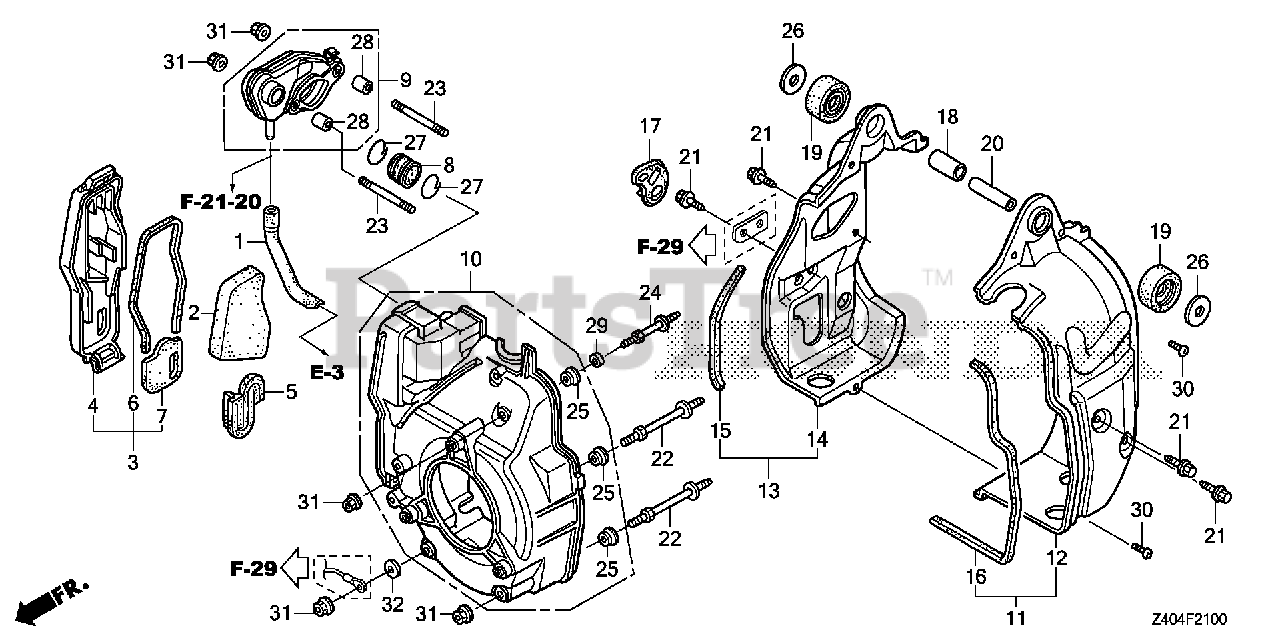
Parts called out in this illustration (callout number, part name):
1	TUBE, BREATHER
2	ELEMENT, AIR CLEANER
3	COVER, AIR CLEANER
4	COVER, AIR CLEANER
5	RUBBER, AIR CLEANER
6	SEAL A, AIR CLEANER COVER
7	SEAL B, AIR CLEANER COVER
8	TUBE, AIR CLEANER CONNECTING
9	JOINT, AIR IN.
10	COVER, FAN
11	SHROUD ASSY., R.
12	SHROUD, R.
13	SHROUD ASSY., L.
14	SHROUD, L.
15	SEAL A, SHROUD
16	SEAL B, SHROUD
17	RUBBER, OIL CHECK
18	COLLAR D, INSULATOR
19	INSULATOR, SHROUD
20	COLLAR B, INSULATOR
21	BOLT, FLANGE (5X10)
22	BOLT A, STUD
23	BOLT, STUD (5X91)
24	BOLT B, STUD
25	COLLAR, REFLECTOR SETTING
26	WASHER, SPROCKET SETTING
27	CLIP (28MM)
28	COLLAR, AIR CLEANER HOUSING
29	COLLAR, DISTANCE
30	SCREW, PAN (4X6)
31	NUT, FLANGE (5MM)
32	WASHER, PLAIN (5MM)
